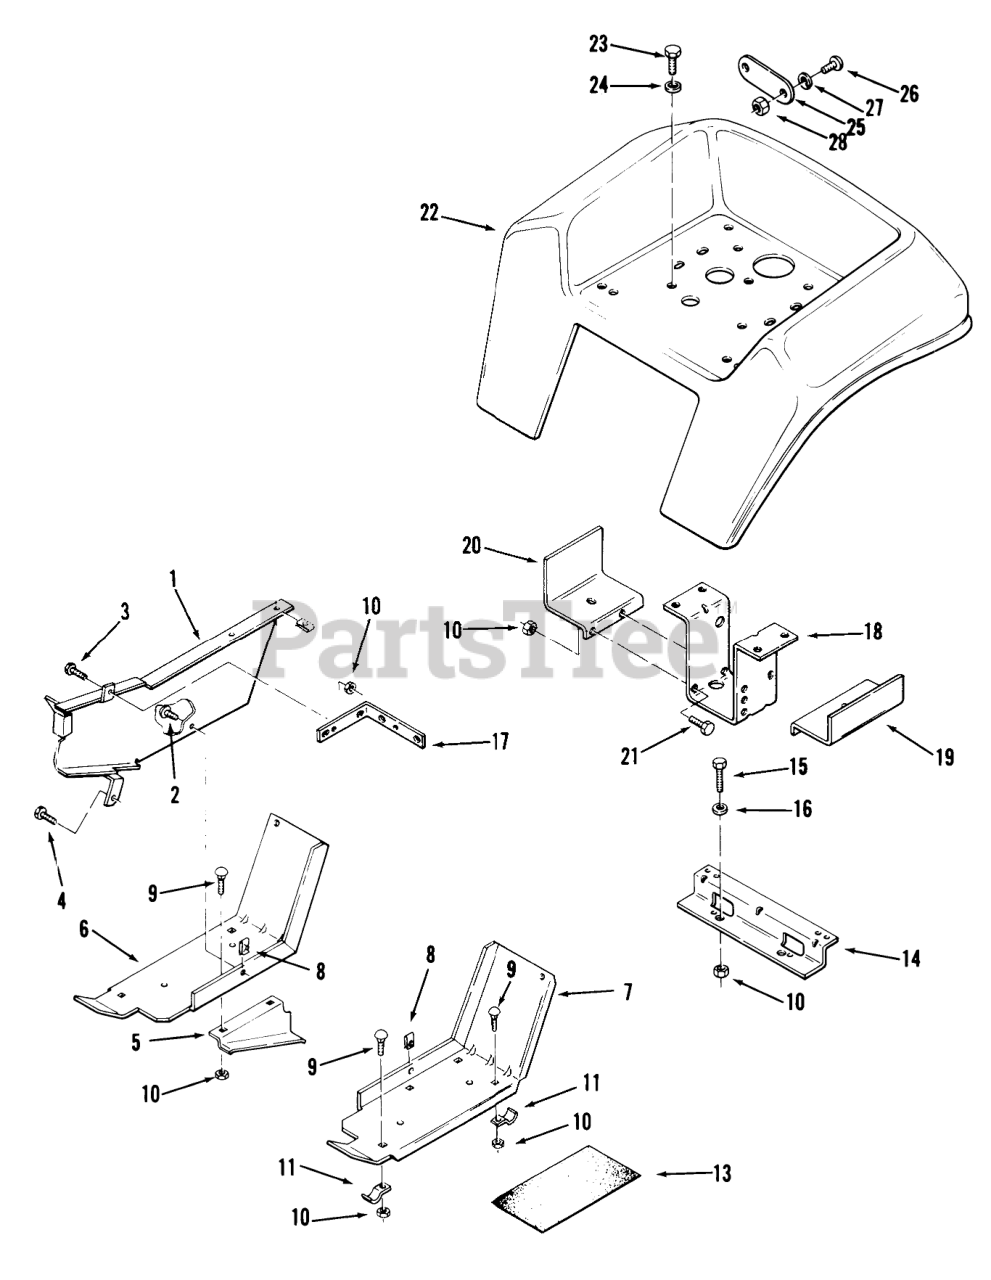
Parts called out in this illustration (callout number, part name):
1	Belt Guard
1	ASSY-BELT GUARD 8 R
2	Screw
3	Bolt
4	SCREW
5	GUID-LOWER BLTR
6	Footrest-RH
7	FOOTREST LH R
9	CARRIAGE BOLT -4
10	Nut
11	BRACKET
13	PAD-FOOTREST
14	BRACKET-FENDER B
15	Bolt
16	WASHER 5/16 SAE
17	Support Bracket-Belt Guard
17	Support Bracket-Belt Guard C-161 Twin Only
18	Fender Support Bracket
19	Fuel Tank Support LH
20	Support-FueITank RH
21	Bolt
22	Fender
23	Bolt
24	Collar
25	REFLECTOR-STICK ON
26	Screw
27	Lockwasher
28	Nut
